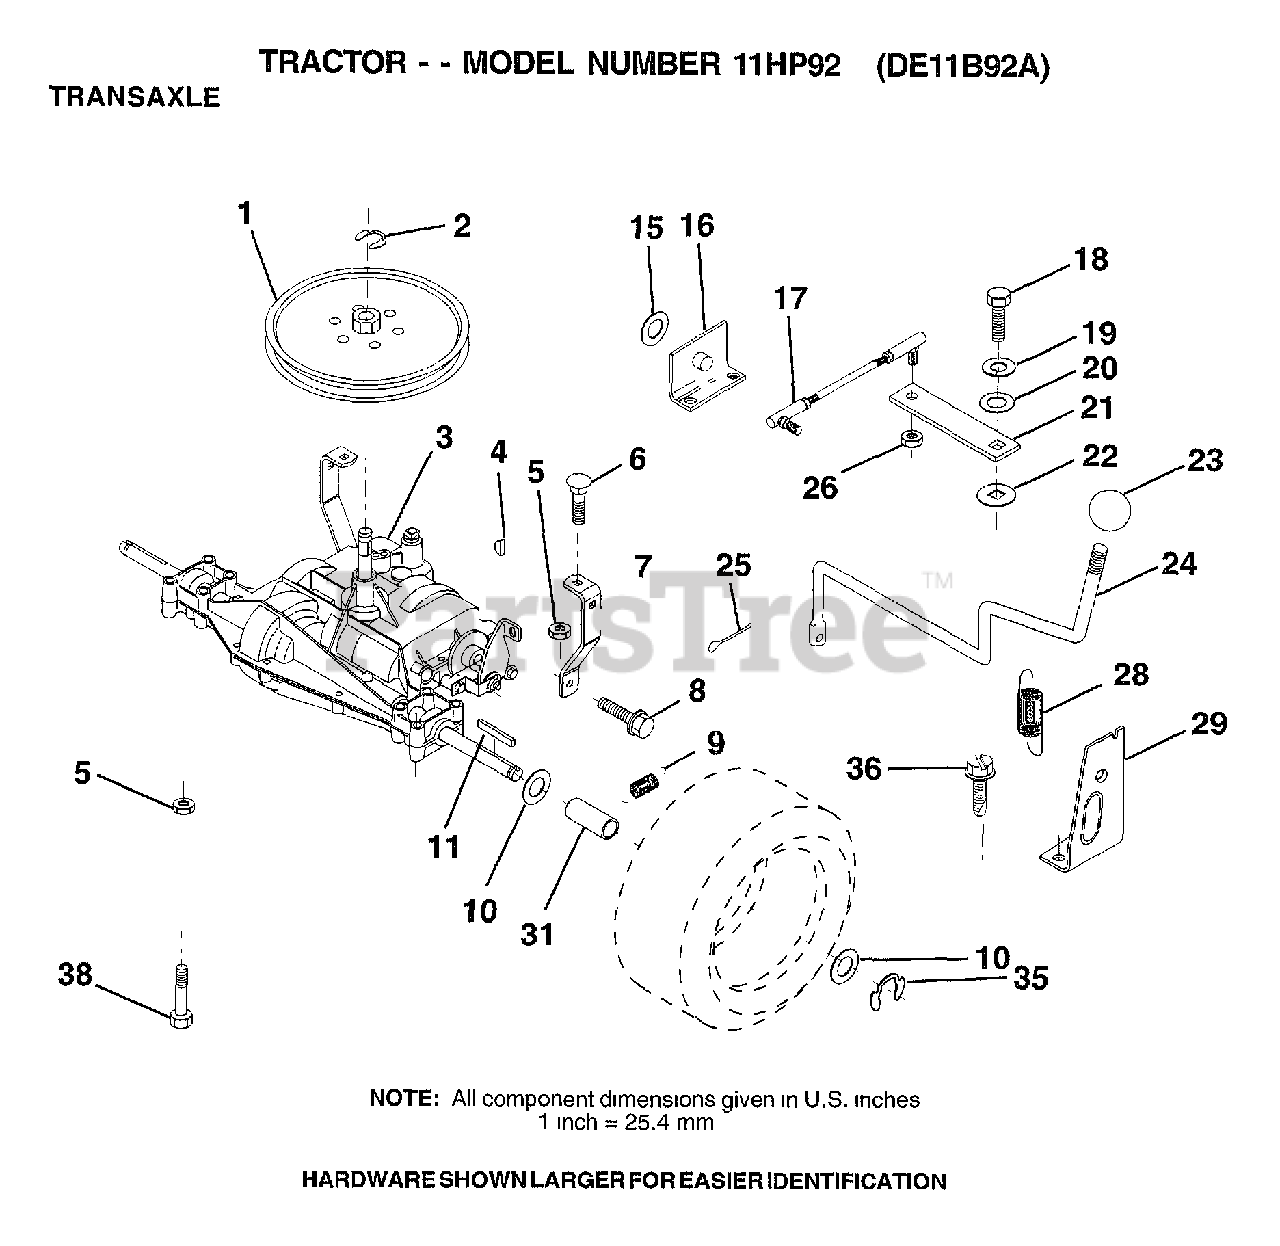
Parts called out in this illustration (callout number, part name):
1	PULLEY
6	BOLT
7	"STRAP,TORQUE"
8	SCREW
9	SPRING.BRAKE.RETU
10	WASHER
11	SQUARE KEY
16	SUPPORT HANDLE SHIFT LH
17	LINK SHIFT
18	BOLT.1/4-28.W/PAT
19	LOCKWASHER
20	WASHER LT
22	WASH-SHFT PLT LT
23	KNOB T (1/2-HOLE)
24	"ROD,SHIFT"
25	PIN COTTER 1/8
26	NUT.LOCK.5/16-24
28	"SPRING,EXT"
29	"SUPT,HDLE RH"
31	SPACER AXLE
35	E-RING LT
36	SCREW
38	BOLT.HEX.FLGHD
